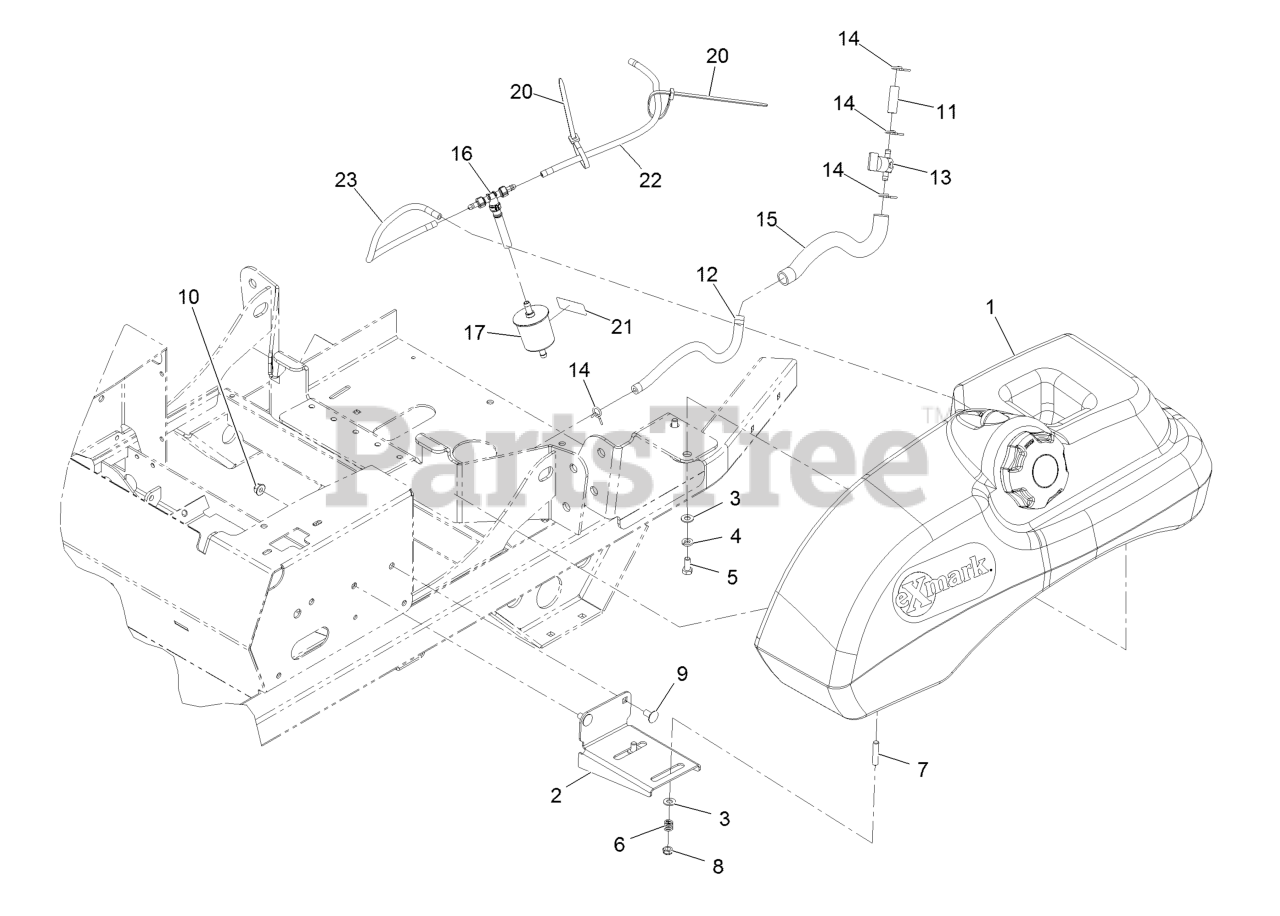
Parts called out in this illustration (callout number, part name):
1	ASM-FUEL TANK
2	BRACKET-TANK AND FENDER
3	WASHER-PLAIN
4	WASHER-LOCK
5	SCREW-HH
6	SPRING-TANK, FUEL
7	STUD
8	NUT-LOCK, NI
9	SCREW-CARR
10	NUT-HF, NI
11	HOSE-FUEL
12	HOSE-FUEL
13	VALVE-FUEL
15	CONDUIT-FUEL LINE
16	TEE AND CHECK
17	FILTER-FUEL
20	TIE-PLASTIC
21	DECAL-FILTER, EMISSIONS
22	HOSE,EMISSIONS
23	HOSE-EMISSIONS
